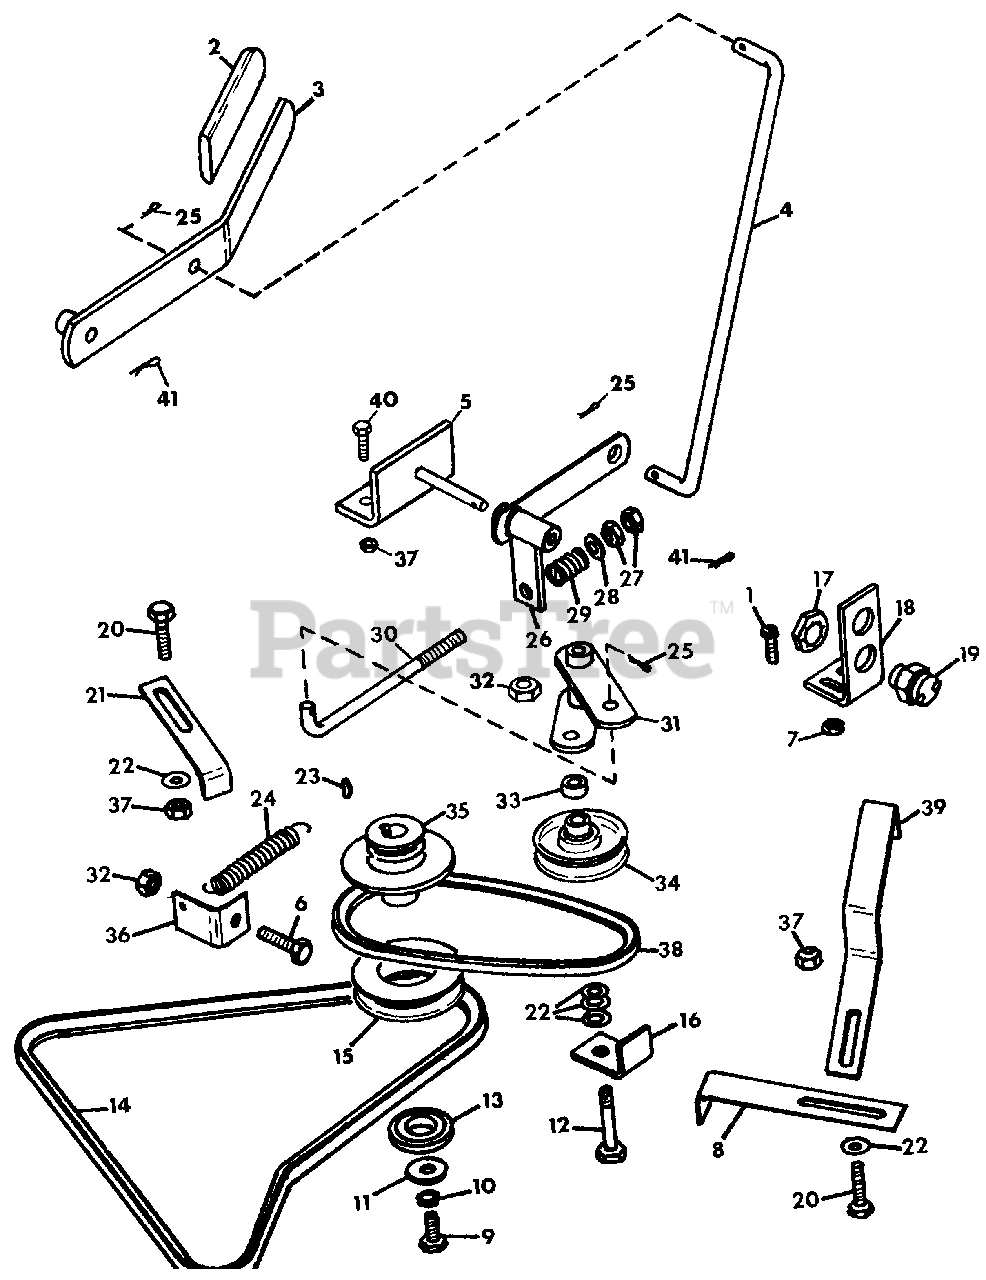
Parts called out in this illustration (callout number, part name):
1	SCREW, MACH. 10-24X1.50
2	GRIP, PTO LEVER
3	WELDMENT, PTO CONTROL HANDLE
4	ROD, PTO CONTROL
5	WELDMENT, PTO HAND LEVER BRKT.
6	BOLT, HEX 3/8-16X1.00
7	NUT, LOCK 10-24
8	BELT GUIDE, REAR CLUTCH HUB
9	BOLT, HEX 7/16-20X2.00
10	WASHER, LOCK 7/16
11	WASHER, SPECIAL FLAT
12	BOLT, HEX 3/8-16X2.25
13	BEARING, BALL 1.574X3.149X.708
14	BELT, MOWER
15	SHEAVE, MOWER CLUTCH
16	BELT GUIDE, PTO IDLER
17	NUT, STAMPED 9/16-18
18	BRACKET, INTERLOCK SWITCH
19	SWITCH, INTERLOCK
20	BOLT, HEX 5/16-18X1.75
21	BELT GUIDE, FRONT CLUTCH HUB
22	WASHER, FLAT .344X.688X.065
23	KEY, SQUARE .250X1.250
24	SPRING, PTO RETURN
25	PIN, COTTER .063X1.00
26	WELDMENT, PTO CLUTCH LEVER
27	NUT, HEX 3/8-16
28	WASHER, FLAT .406X.812X.065
29	SPRING, COMP. 1.0X.78
30	ROD, PTO CLUTCH ACTUATING
31	WELDMENT, PTO CLUTCH ACTUATING
32	NUT, LOCK 3/8-16
33	SPACER
34	PULLEY
35	WELDMENT, CLUTCH HUB
36	TAB, PTO RETURN SPRING
37	NUT, LOCK 5/16-18
38	BELT, PTO CLUTCH
39	BELT GUIDE, PTO CLUTCH
40	BOLT, HEX 5/16-18X.75
41	PIN, COTTER .094X.625
